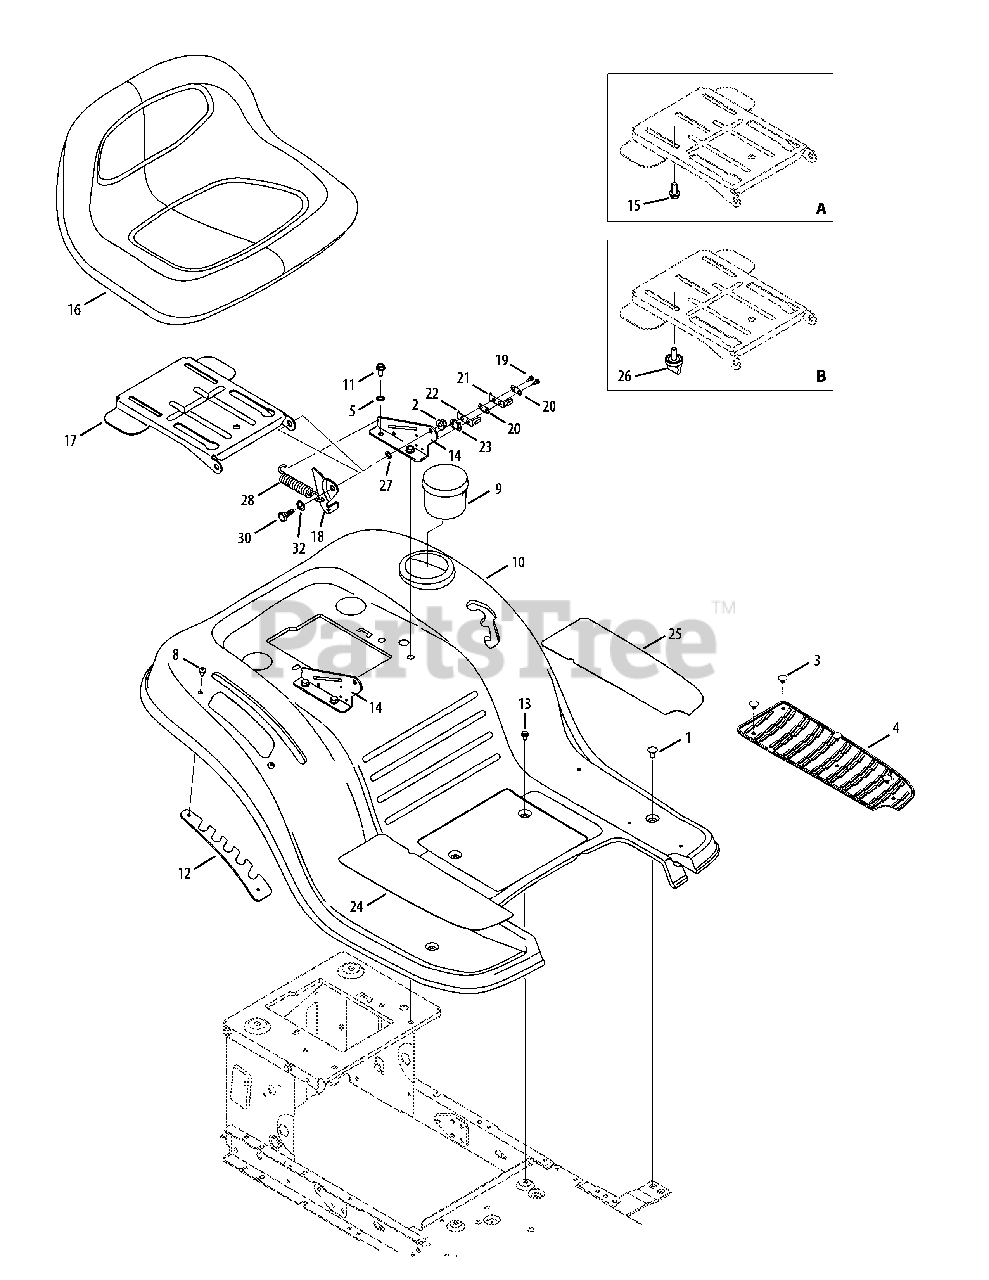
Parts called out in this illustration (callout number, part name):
1	Carriage Bolt 1/4-20 x .62
2	Flange Locknut 5/16-18 Gr. F, Nylon
3	Ratchet Clip
4	Foot Pad, RH
4	Foot Pad, LH
5	Lockwasher 5/16 ID
6	Flat Washer .510 x .750 x .033
8	Tap Screw 1/4-20 x .50
9	Cup Holder
10	Fender - Orange
11	S-Tapp Scr 5/16-18 x .75
12	Lift Adjustment Bracket
13	Hex Wash S-Tapp Scr 1/4-20 x .50
14	Seat Mounting Bracket
15	Screw 3/8-16 x .875
16	Seat, Low Back
16	Seat, Medium Back
16	Seat, High Back
17	Seat Pivot Bracket
18	Seat Lift Bracket
19	Hex Wash HD AB S-Tapp Scr #8-.50
20	Insulator Plate
21	Spring Switch
22	Seat Spring Switch
23	Insulator Plate
24	Foot Pad, Abrasive, RH
25	Foot Pad, Abrasive, LH
27	Cupp. Washer .345 ID x .88 OD x .060
28	Extension Spring .84 Dia. x 4.6
30	Shoulder Screw
32	Flat Washer .510 x .75 x .033
